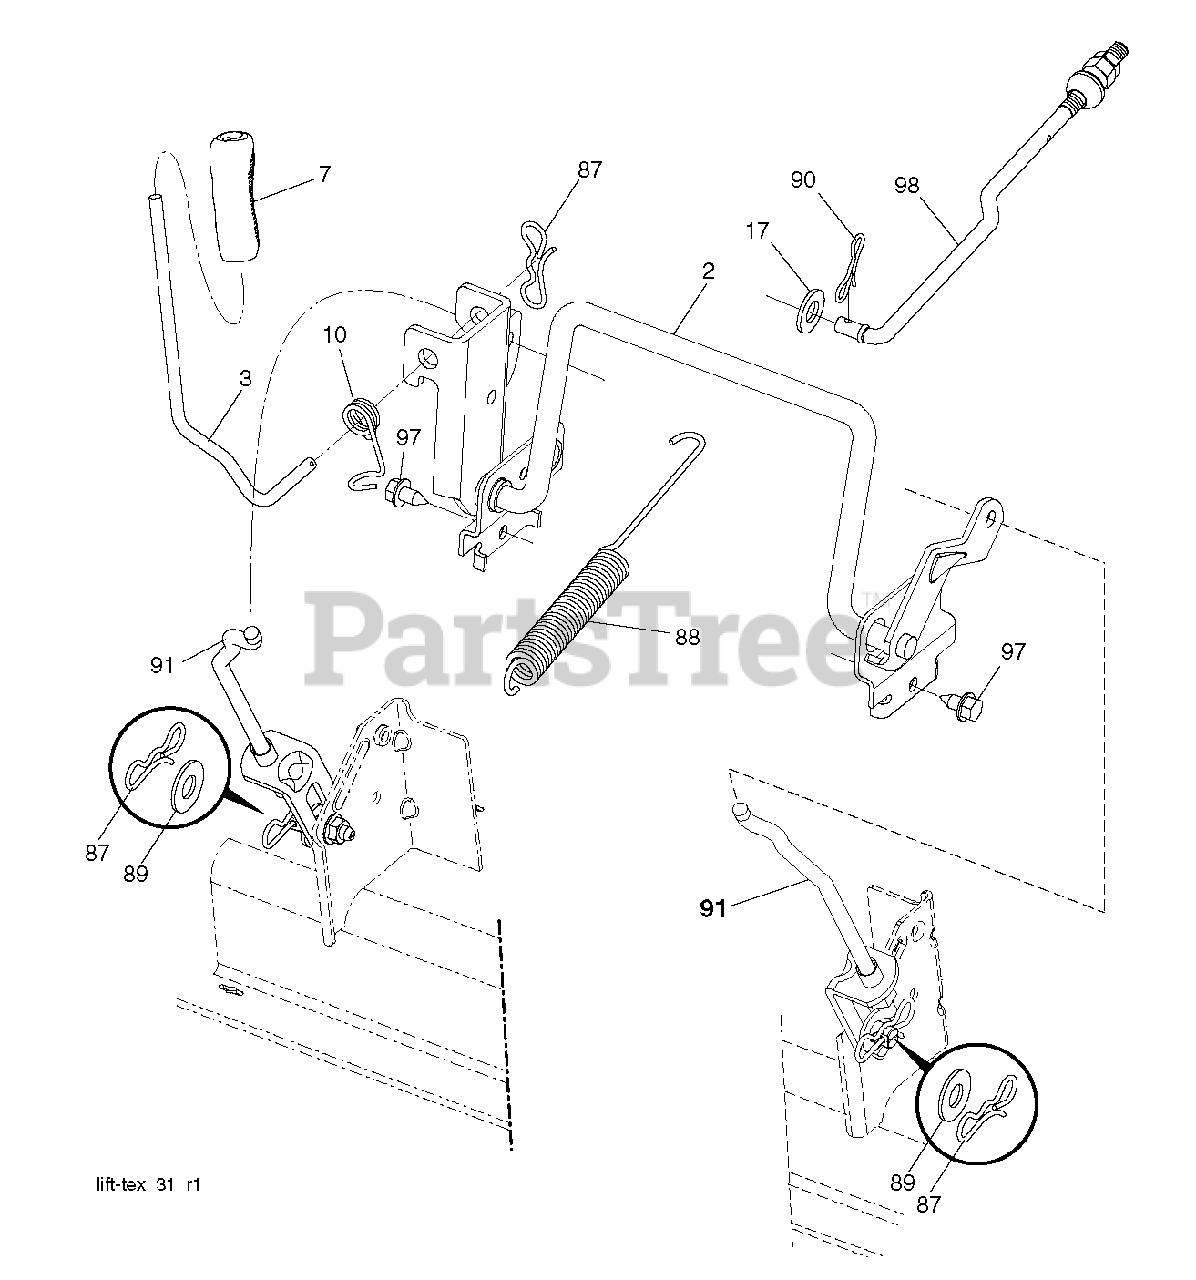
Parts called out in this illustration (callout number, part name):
2	SHAFT LIFT DECK WELD
3	LEVER.LIFT.HANDLE.LT
7	GRIP.HANDLE.LIFT.PVC.BLACK
10	SPRING.TORSION.LIFT.HANDLE
17	WASHER
87	PIN.COTTER.7/16.BOW TI.
88	SPRING.DK.LIFT.97/107.TXCRDII
89	WASHER.CLEAR.ZINC
90	PIN.COTTER.5/16.BOW TI
91	LINK.ASM.LIFT.REAR
98	LINK.ASM.SUSP.FRONT.MW
